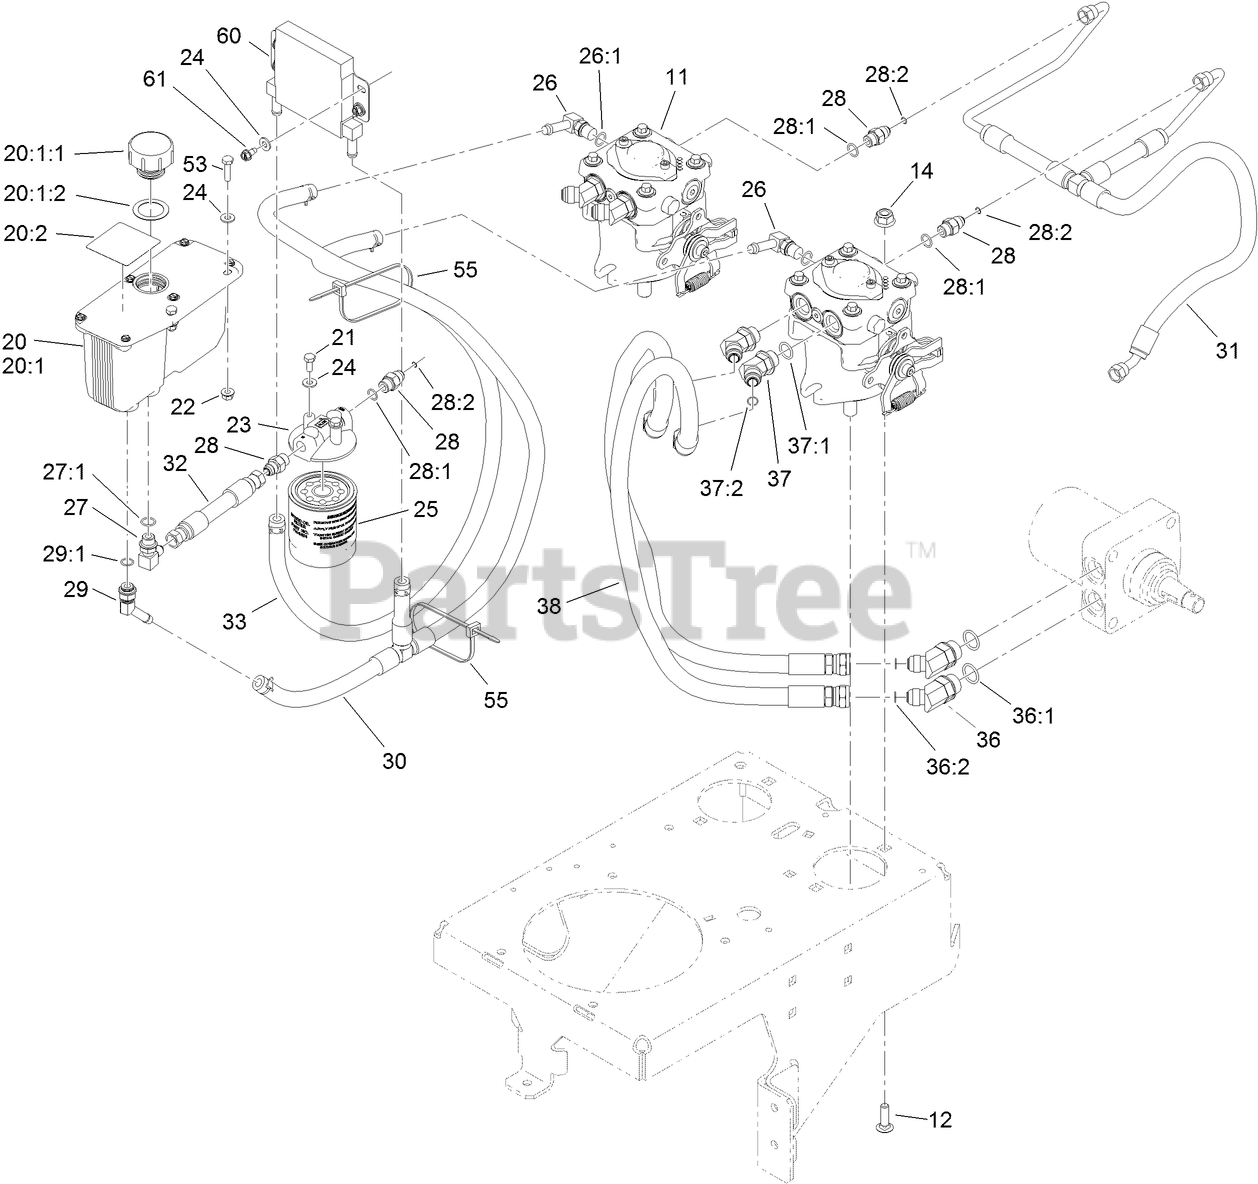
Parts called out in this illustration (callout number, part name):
11	HYDRAULIC PUMP ASM
12	BOLT-CARR
14	NUT-HF, NI
20	HYD RESERVOIR ASM
20:1	Reservoir-HYD
20:1:1	CAP-RESERVOIR, HYD
20:1:2	GASKET-CAP
20:2	DECAL-WARNING
21	SCREW-HH
22	NUT-HHF
23	HEAD-FILTER
24	WASHER-FLAT
25	ELEMENT-FILTER, 25 MICRON
26	FITTING-ELBOW, 90
26:1	O-RING
27	FITTING-ELBOW, 90 DEG
27:1	O-Ring
28	FITTING-STRAIGHT
28:1	O-Ring
28:2	O-RING
29	FITTING-BARBED, 45 DEG
29:1	O-RING
30	CASE DRAIN HOSE ASM
31	CHARGE HOSE ASM
32	HYD HOSE ASM
33	CASE DRAIN HOSE ASM
36	FITTING-HYD, 45 DEG
36:1	O-RING
36:2	O-Ring
37	FITTING-HYD, 45 DEG
37:1	O-RING
37:2	O-Ring
38	HYD HOSE ASM
53	SCREW-HH
55	TIE-CABLE
60	COOLER-OIL
61	SCREW-HWH
